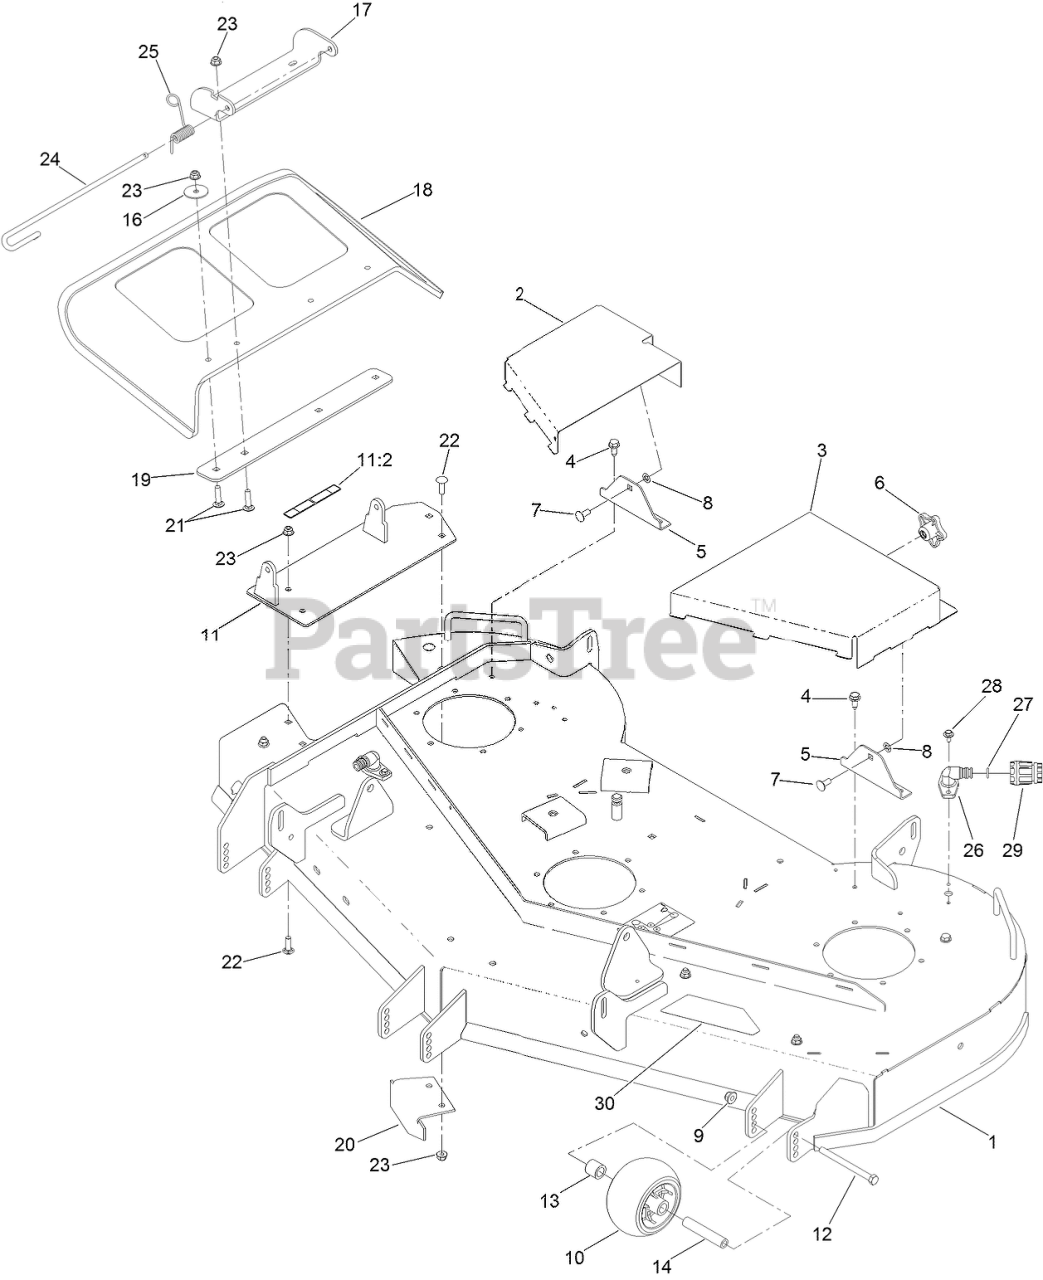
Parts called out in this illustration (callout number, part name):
1	54 INCH DECK ASM
2	COVER-BELT, RH
3	COVER-BELT, LH
4	SCREW-HWHTF
5	BRACKET-SUPPORT
6	KNOB-HANDLE
7	SCREW-CARR
8	RING-RETAINING, BOLT
9	NUT-HF, NI
10	ROLLER-SCALP, ANTI
11	PIVOT-DEFLECTOR
11:2	DECAL-DANGER
12	SCREW-HH
13	SPACER-AXLE, REAR
14	TUBE-SPANNER
16	WASHER-FLAT
17	BRACKET-DEFLECTOR, UPPER
18	DEFLECTOR
19	PLATE-DEFLECTOR
20	BAFFLE-CUTOFF
21	SCREW-CARR
22	SCREW-CARR
23	NUT-HF, NI
24	PIN-CHUTE
25	SPRING-TORSION
26	FITTING-WASHOUT
27	O-RING
28	SCREW-HHFTF
29	CONNECTOR-HOSE
